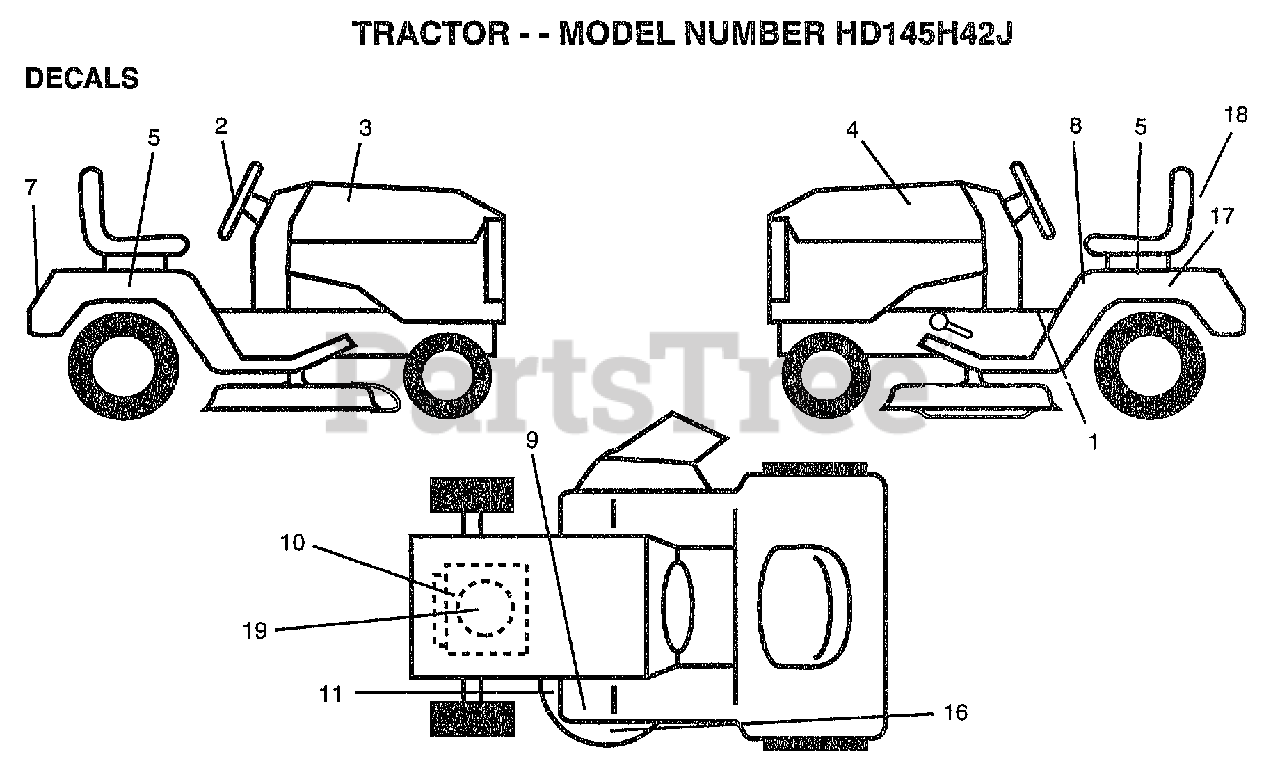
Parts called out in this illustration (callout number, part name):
1	"DECAL-SADDLE,INST"
2	"DECAL WHEEL,STEER"
3	"DECAL-HOOD,RH"
4	"DECAL-HOOD,LH"
5	"DECAL FENDER,SD"
7	"DECAL FENDER,LOGO"
8	"DECAL FENDER,DANG"
9	DECAL CLUT/BRAKE
10	DECAL.ENGINE
11	"DECAL-SCHEM,BELT"
16	"DECAL DECK,MULCH"
17	DECAL.BATRY.3-3908
18	"DECAL SEAT,ACC"
19	DECAL.ENGINE.STET
